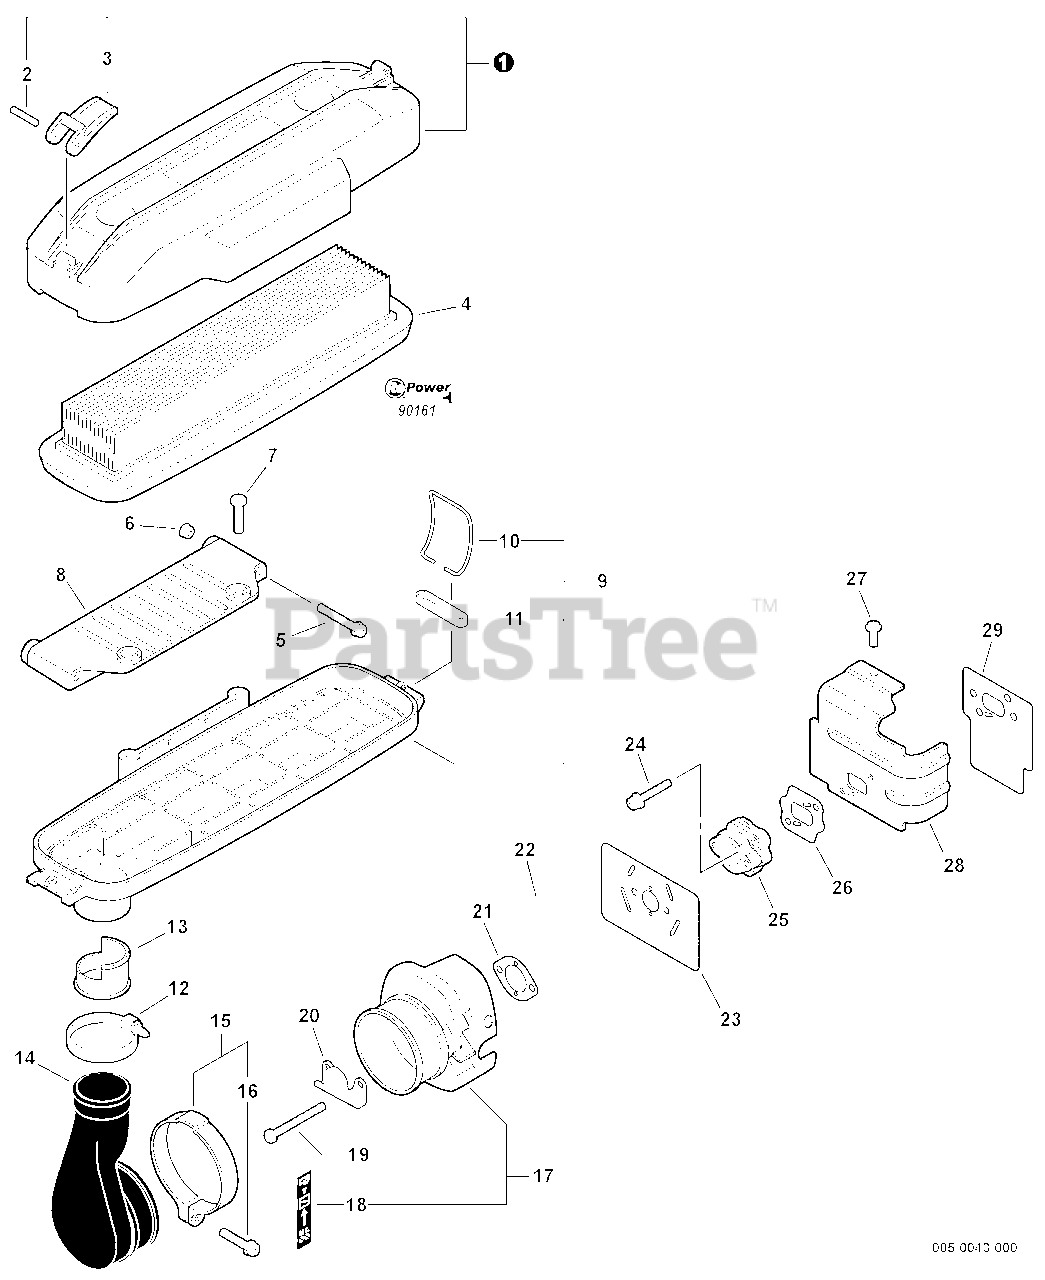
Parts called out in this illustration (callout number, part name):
1	AIR FILTER COVER ASSY
2	PIN - SPRING -- 3X25
4	FILTER, AIR
5	SCREW - 5X40
6	NUT - 5 -- FLANGE
7	SCREW - 5X20
8	BRACKET
9	AIR FILTER CASE ASSY
10	RING, RETAINING
11	RETAINER
12	CLAMP, HOSE
14	ADAPTOR, INTAKE
15	CLAMP KIT
16	SCREW - 5X25
17	BRACKET KIT - PLASTIC
18	LABEL - CHOKE
19	SCREW - 5X60
20	PLATE, PREVENT
21	GASKET, INTAKE
22	CARBURETOR
23	GASKET, INTAKE
24	SCREW - 5X25
25	INSULATOR, INTAKE
26	GASKET, INTAKE
27	SCREW - 5X10
28	COVER, CYLINDER - INTAKE
29	SHIELD, INTAKE
30	RePower TUNE-UP KIT
